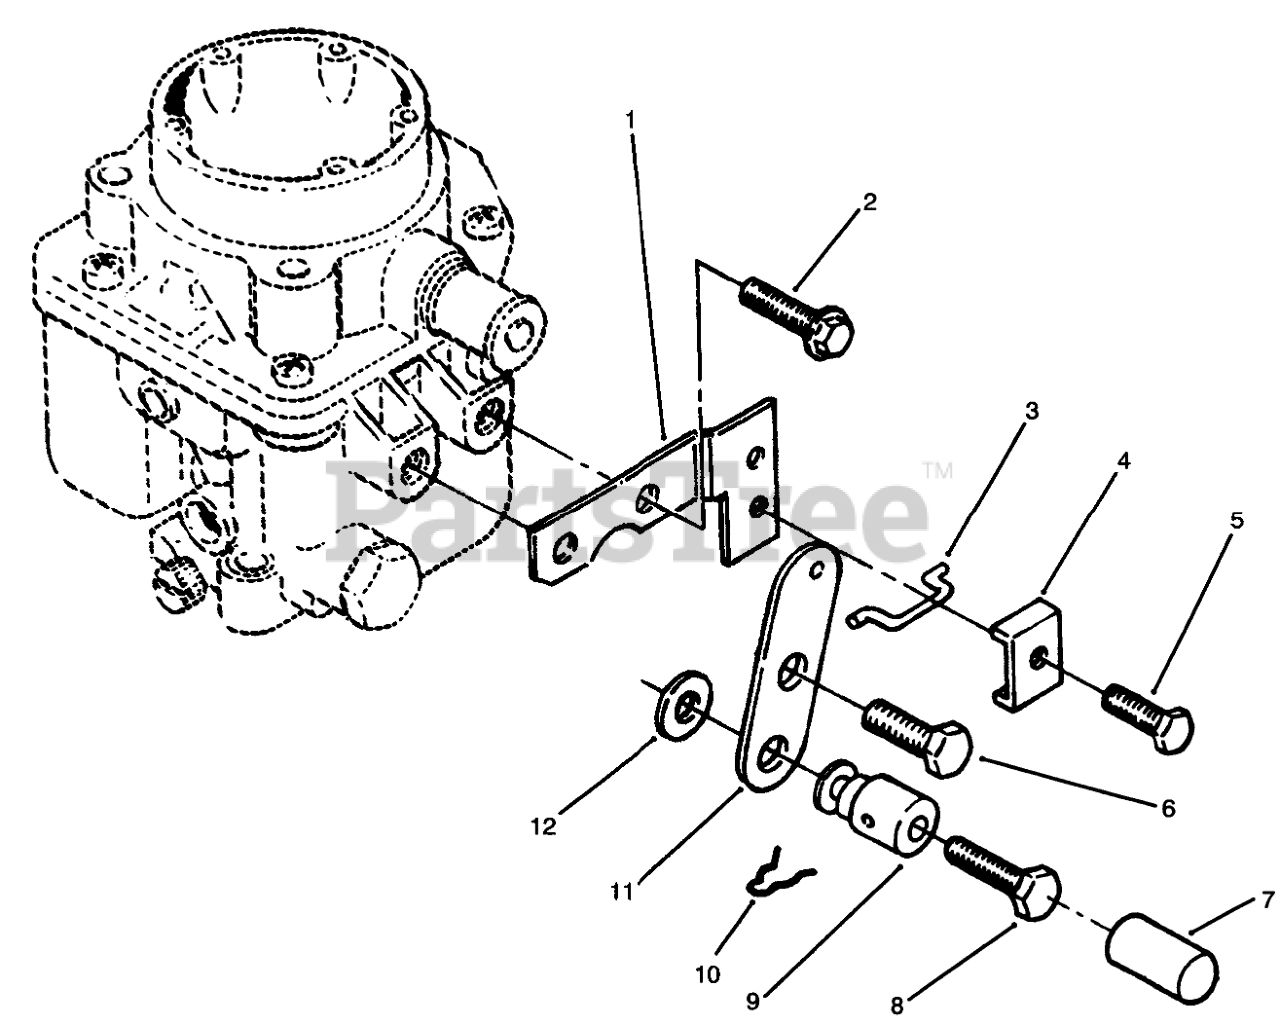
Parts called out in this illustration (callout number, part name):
1	BRACKET
2	SCREW-HWH
3	LINK-CHOKE
5	SCREW-TAPPING
6	MACHINE SCREW
8	SCREW
9	SWIVEL-CHOKE LEVER
10	PIN-COTTER
11	CHOKE-LEVER (PRIMED)
12	Washer
